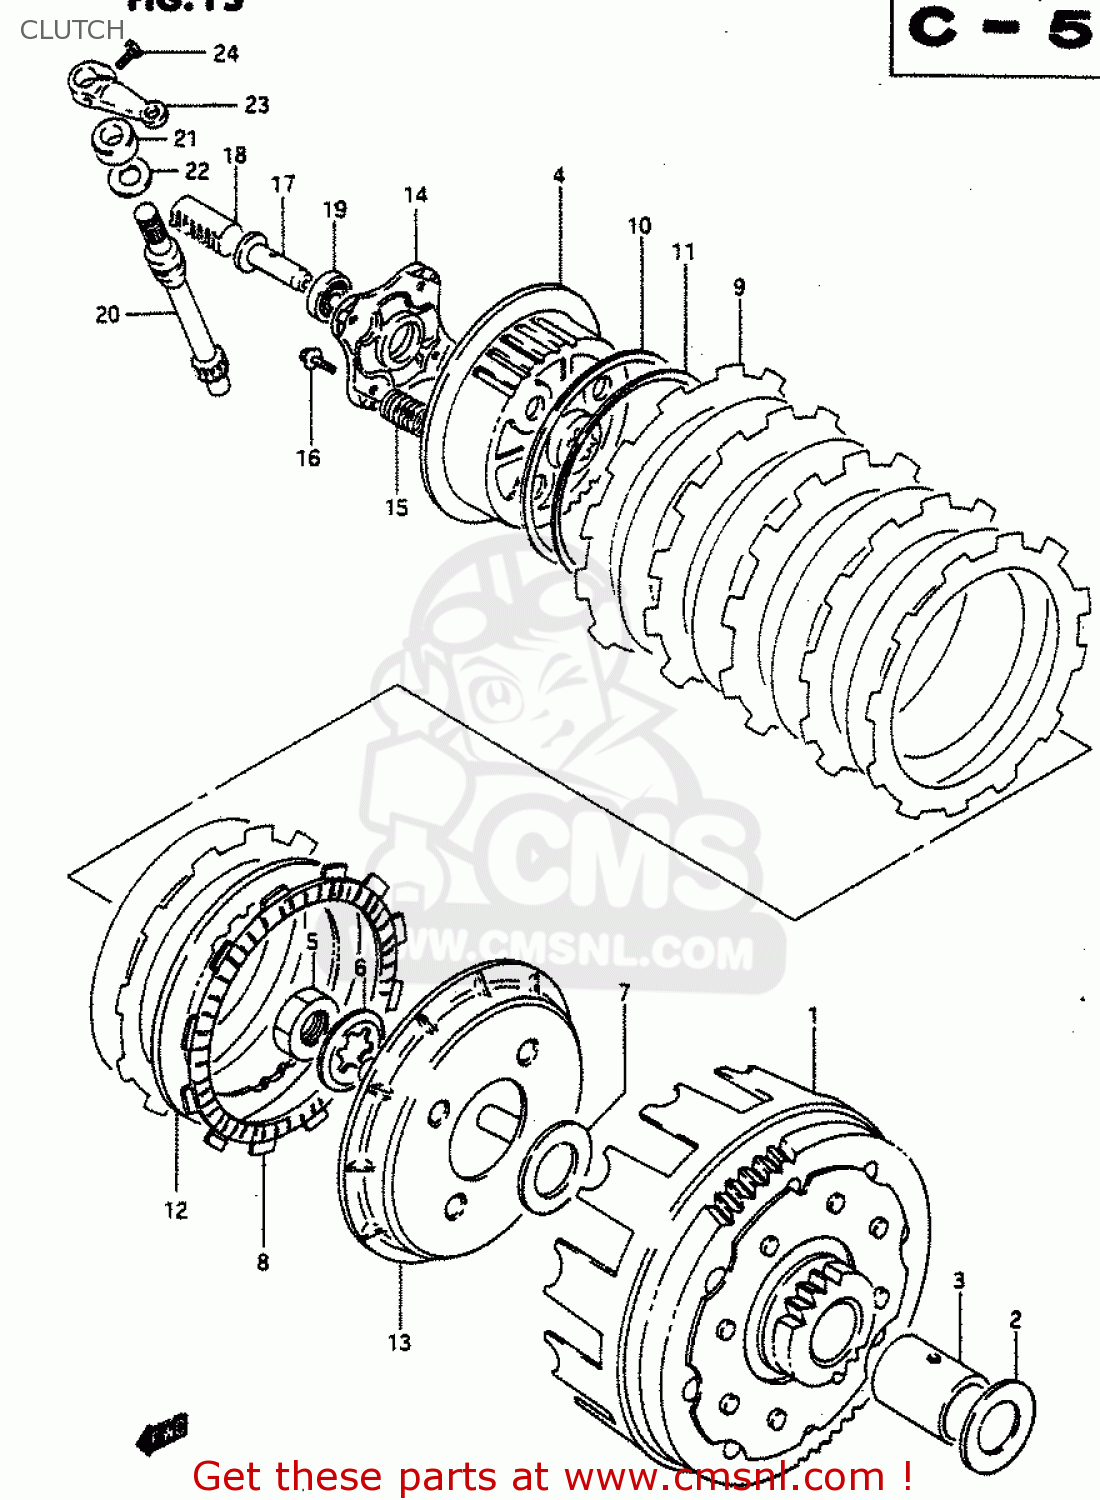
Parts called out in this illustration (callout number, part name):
1	GEAR ASSEMBLY,PRIMARY DRIVE
2	WASHER
3	SPACER(22X28X32.5)
4	HUB,CLUTCH SLEEVE
5	NUT
6	WASHER,LOCK
7	WASHER
8	PLATE,CLUTCH DRIVE (NAS)
9	PLATE,CLUTCH DRIVE NO (NAS)
10	SEAT,WAVE WASHER(T:1.4)
11	WASHER
12	PLATE,CLUTCH DRIVEN (NAS)
13	DISC,CLUTCH PRESSURE
14	PLATE,RELEASE
15	SPRING
16	BOLT 6X20
17	PIECE,CLUTCH PUSH
18	RACK,CLUTCH RELEASE
19	BEARING
20	PINION,CLUTCH RELEASE
21	SEAL,OIL (12X22X9)
22	WASHER (14.2X22X1)
23	ARM,CLUTCH RELEASE
24	BOLT
